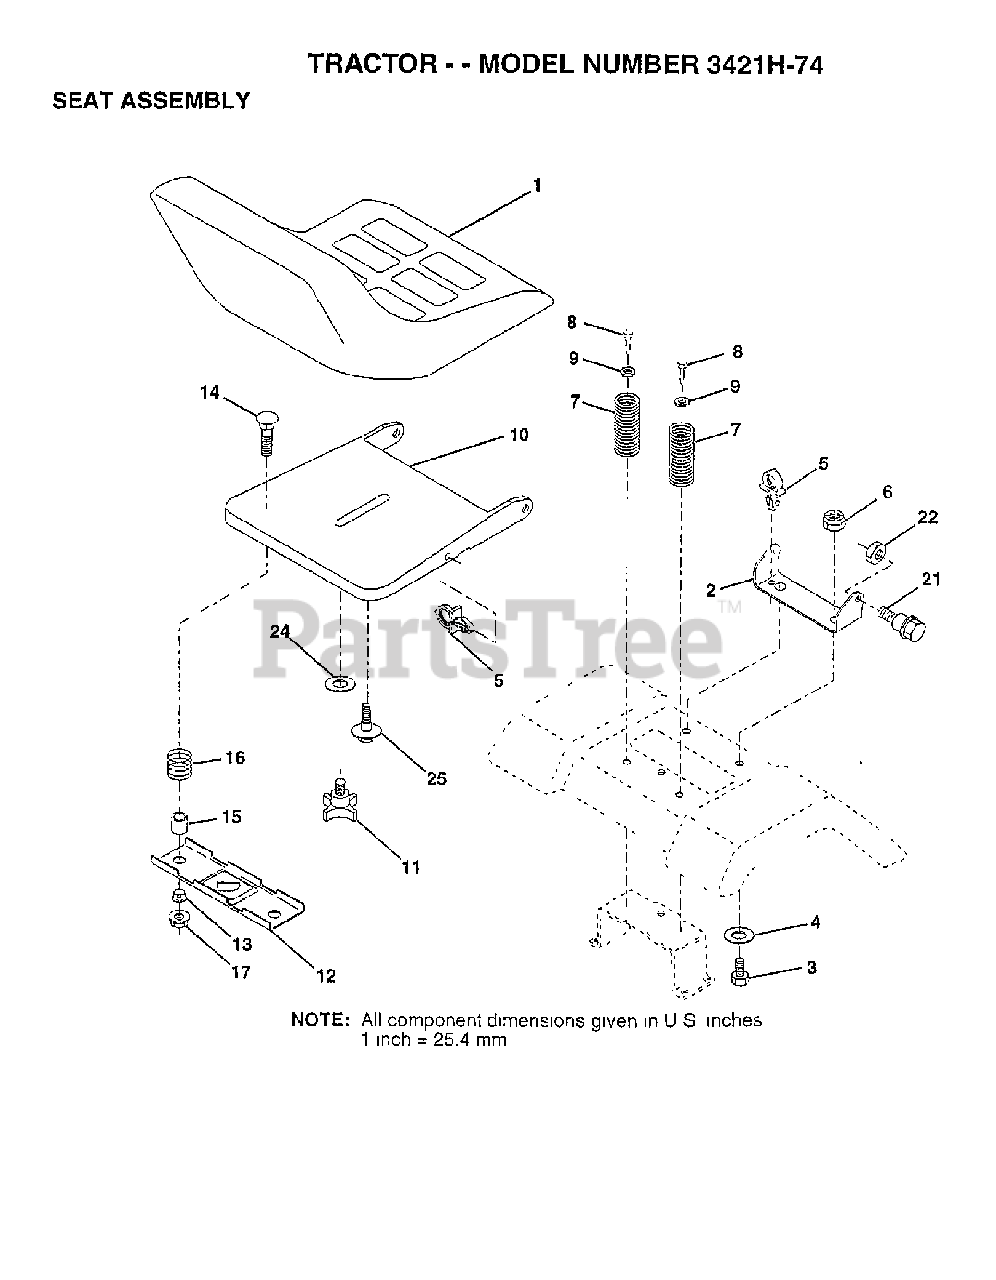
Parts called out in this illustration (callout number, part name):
2	BRKT,SEAT PIVOT**
3	BOLT
4	WASHER PM
5	PUSH CLIP
6	NUT
7	SPRING COMPRESSION
8	SCREW GTV
12	BRKT SWITCH
14	BOLT CARRIAGE 1/4-20X1 3/8
15	SPACER SPLIT
16	SPRING COMPRESSED
17	NUT T
22	LOCKNUT
25	BOLT, SHOULDER**
